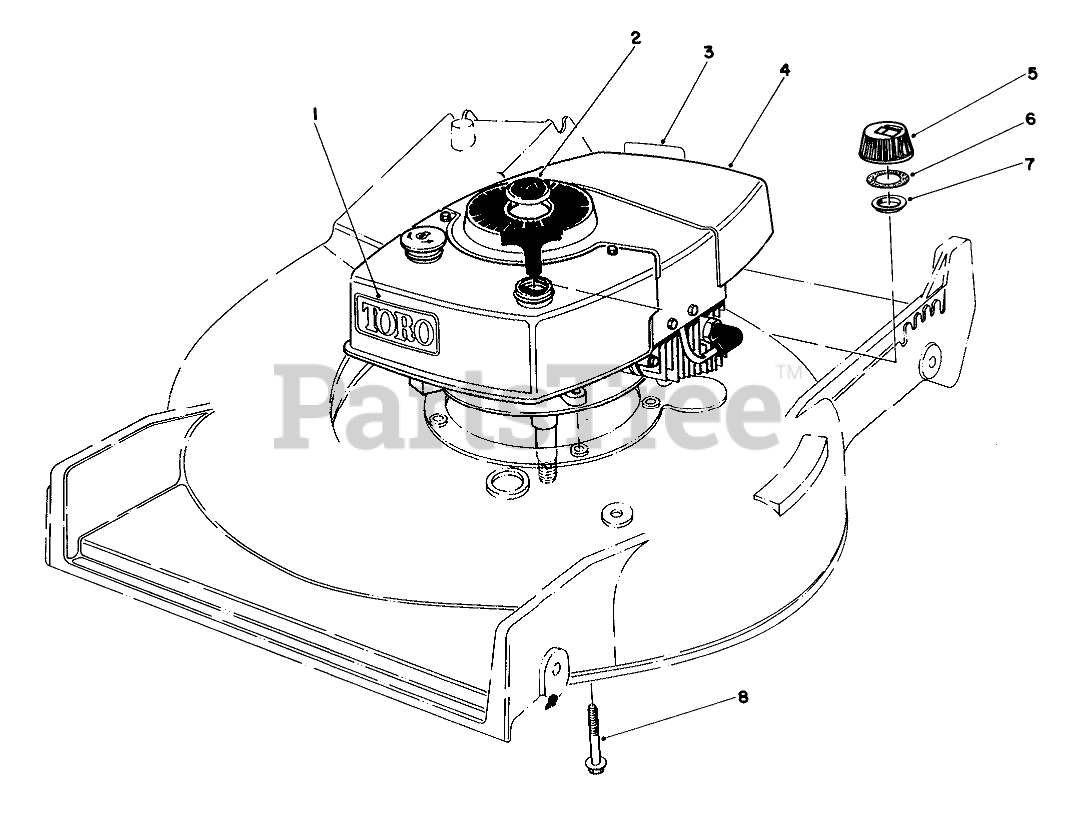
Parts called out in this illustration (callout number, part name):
1	Decal Tow
2	PLUG BUTTON
3	Decal-Maintenan
4	Engine
5	Gas Cap Assembly (Incl. Ref. #6 & 7)
6	GASKET
7	GAS CAP BAFFLE
8	3/8-16 X 2 CAPSCREW
